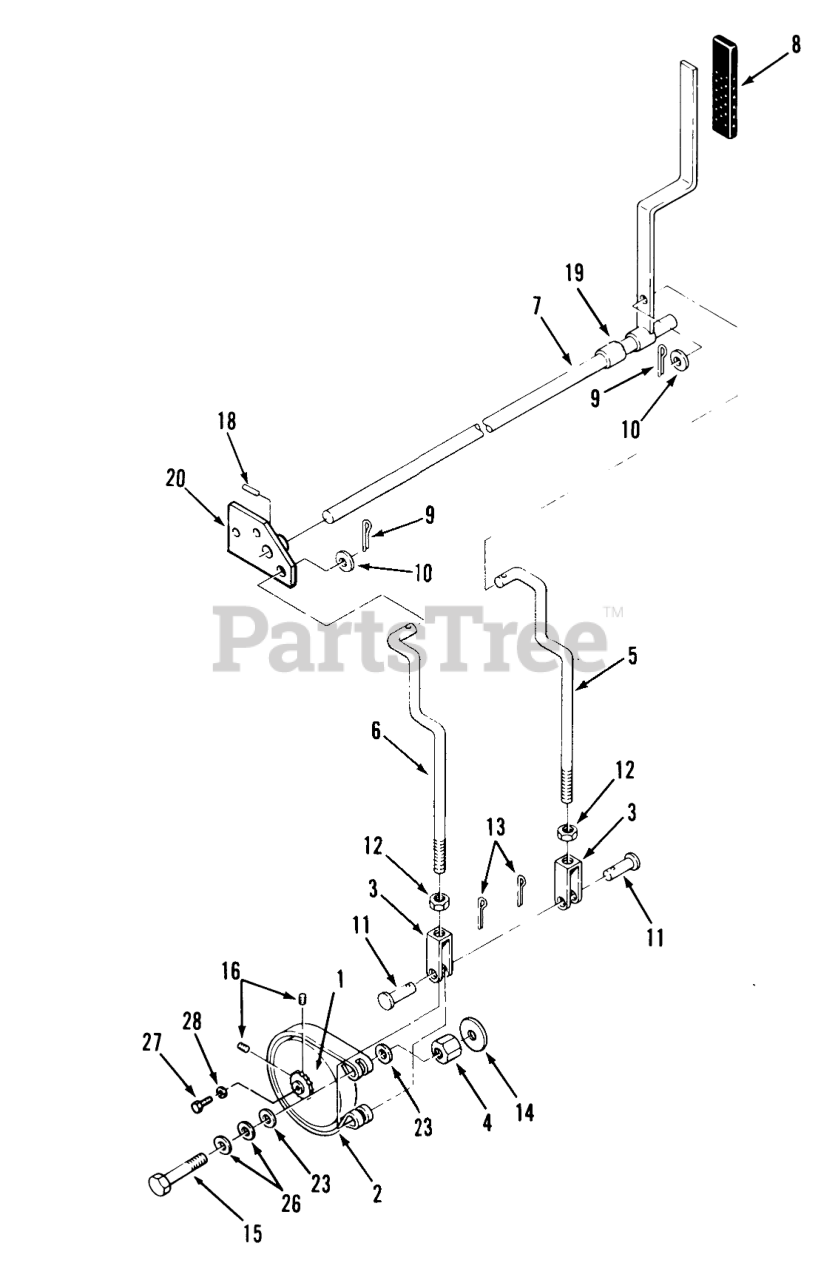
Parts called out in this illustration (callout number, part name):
1	ASS'Y-DRUM SPROCKET
2	BRAKE-BAND
3	ASSY-YOKE BRAKE
4	NUT-COUPLING
5	ROD-BRAKE L.H.
6	ROD-BRAKE R.H.
7	ASSY-PARKING BRK
8	GRIP BRAKE20258-K
9	PIN-COTTER
10	WASHER-PLAIN
11	PIN-CLEVIS
12	NUT-HEX
13	PIN-COTTER
14	WASHER
15	SCREW-HH
16	SCREW-HSH
18	SPIROL PIN H D
19	SPACER-PARKING BR B
20	ASSY-PARKING BRK B
23	WASHER-FLAT
26	WASHER-SPRING
27	SCREW-HH
28	WASHER
